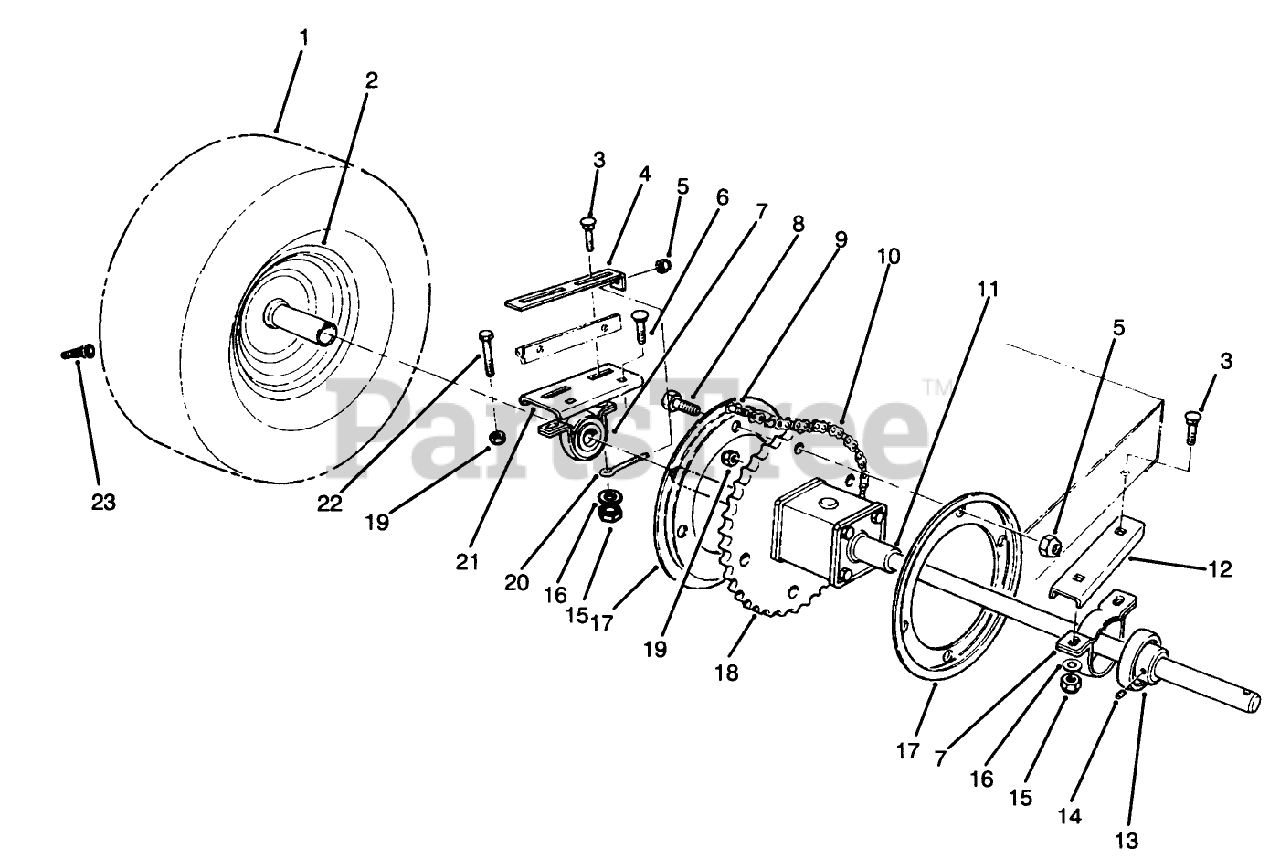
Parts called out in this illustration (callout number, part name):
1	TIRE,PNEU.13X5.00X6
2	WHEEL-REAR
3	SCREW-CARR
4	PLATE-ADJUSTING
5	NUT-LOCK, NI
6	RTNR-PILLOW BLK
7	BOLT-CARR
8	SCREW-HH
9	LINK-CHAIN
10	CHAIN-ROLLER
13	BEARING-BALL
14	SCREW-HSH
15	NUT-LOCK, NI
16	WASHER-FLAT
17	GUIDE-REAR CHAIN
18	SPROCKET
19	NUT-LOCK, NI
20	SCREW-ADJUSTING
21	RH AXLE SUPPORT
22	AXLE MTG BOLT
